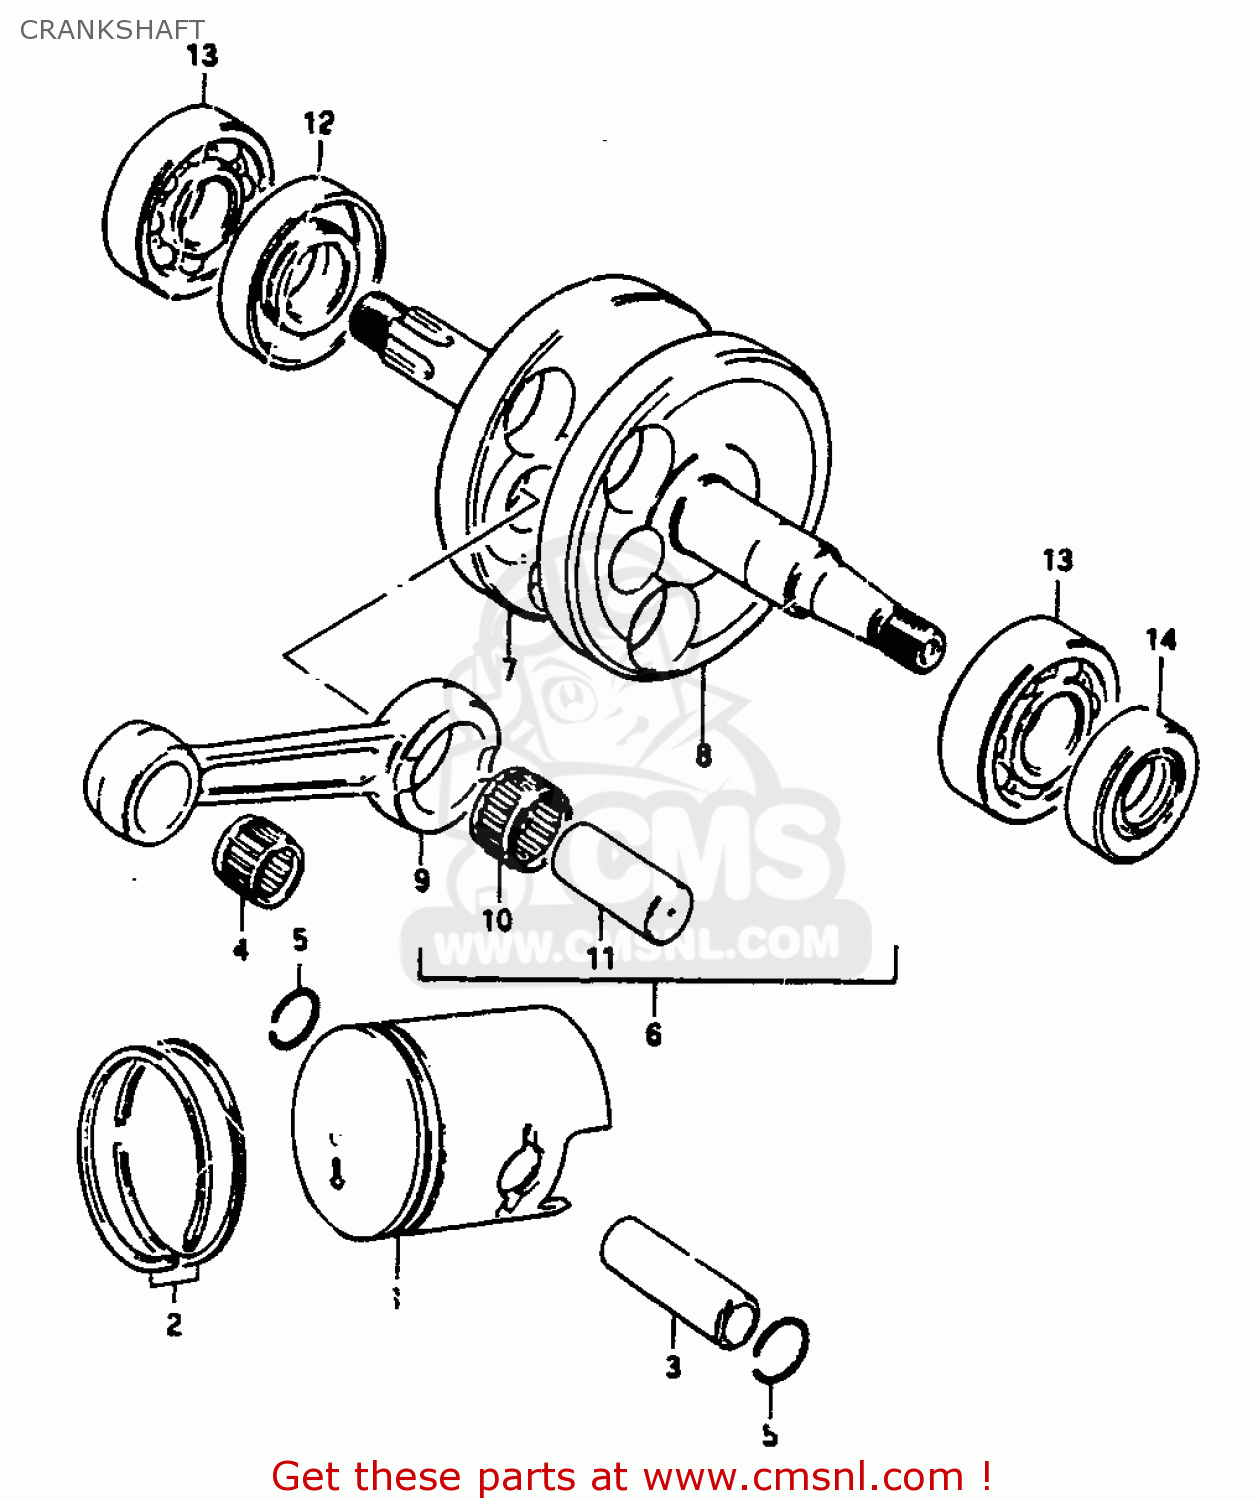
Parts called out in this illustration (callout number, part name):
1	PISTON
2	RING SET,PISTON
3	PIN,PISTON
4	ROLLER BEARING (12X16X1
5	RING,SNAP
6	CRANKSHAFT ASSY
7	CRANKSHAFT,R
8	CRANKSHAFT,L
9	ROD,CONNECTING
10	BEARING(15X21X9.8)
11	PIN,CRANK
12	SEAL,OIL(22X40X8)
13	BEARING(17X40X12)
14	OIL SEAL (17X29X7)
